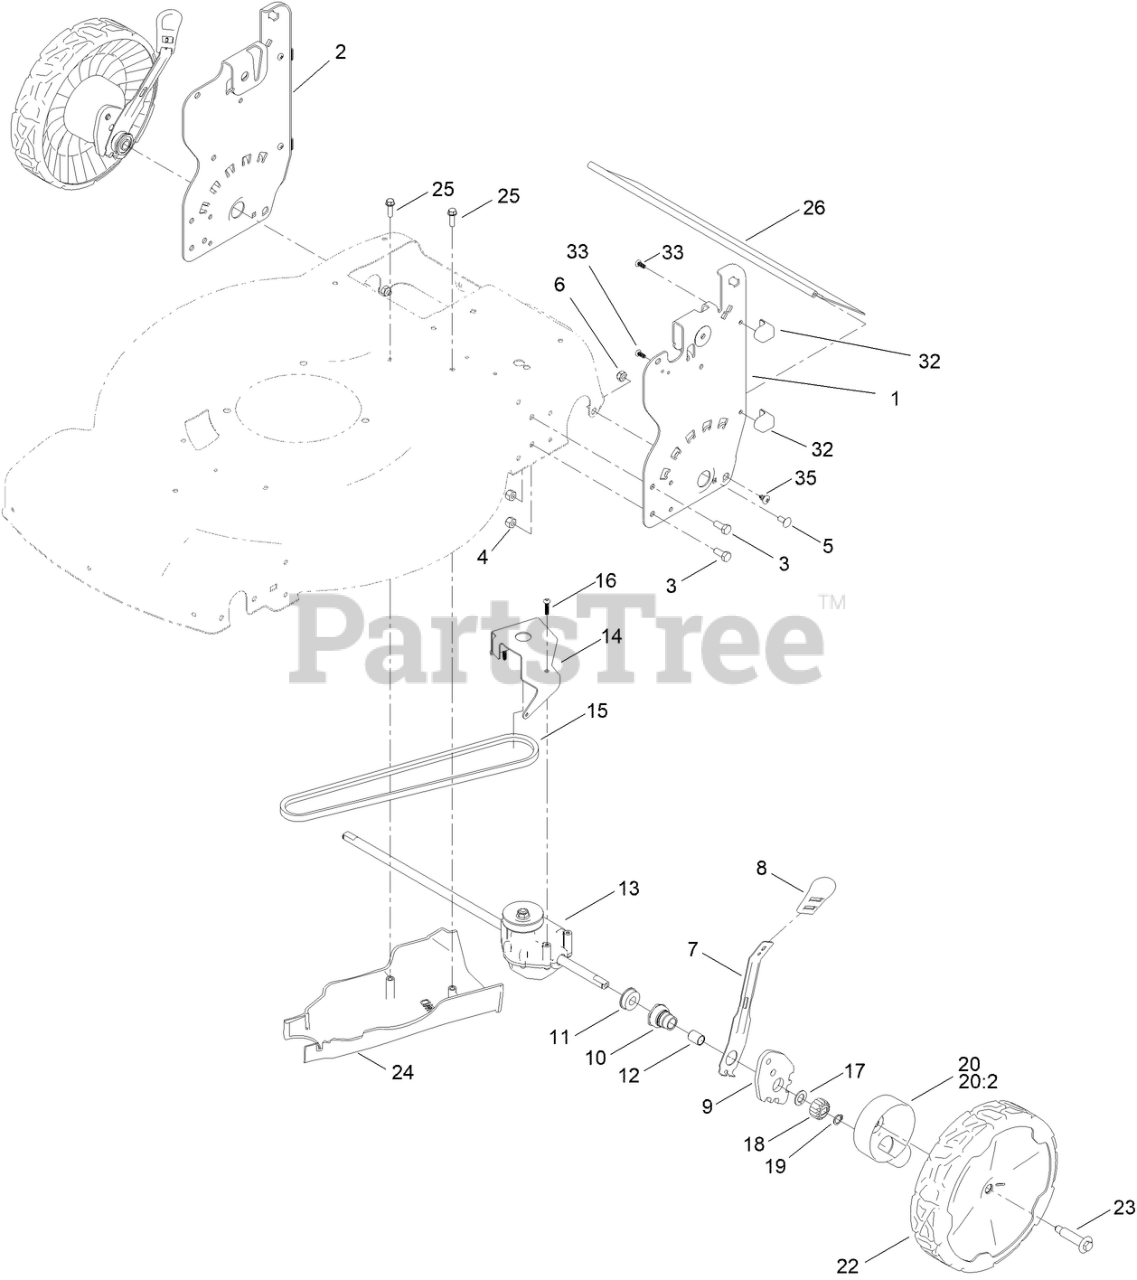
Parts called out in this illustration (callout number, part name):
1	PLATE-HOC, LH
2	PLATE-HOC, RH (2 HOLE)
3	SCREW-HH
4	NUT-LOCK, NI
5	SCREW-CARR
6	NUT-LOCK, NI
7	ARM-SPRING
8	KNOB-HOC
9	ARM-PIVOT, REAR
10	RETAINER-BUSHING, HOC
11	BEARING-BALL
12	BUSHING-SLEEVE
13	TRANSMISSION-RWD
14	BRACKET-TRANSMISSION
15	V-BELT
16	SCREW-PLASTITE
17	WASHER-THRUST
18	GEAR-PINION, 15T
19	RING-RETAINING
20	ASM-COVER, GEAR (DK GRAY)
20:2	WASHER-STEPPED
22	ASM-9.65" WHEEL, GEARED
23	WHEEL BOLT
24	COVER-BELT, RWD
25	SCREW-HWH
26	SHIELD-TRAILING
32	PAD-SMART STOW
33	SCREW-PLASTITE
35	SCREW-PTH
